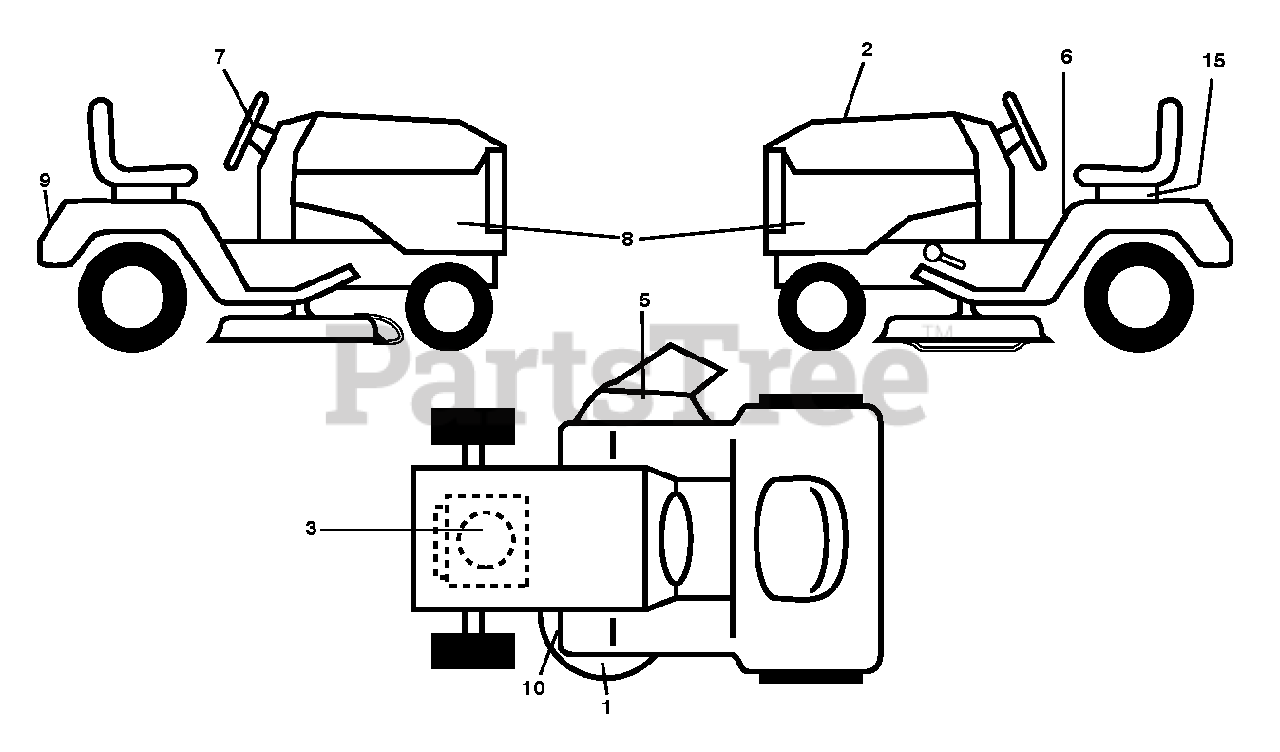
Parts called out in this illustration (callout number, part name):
1	DECAL.PPRO.10YRDECKWAR.POP
2	DECAL.RPL.BSM31.PB.TLW.46C.K46
3	Decal, Engine BS 17_5PB DOM 381669
5	DECAL, DECK DEFLECTOR, WARNING
6	DECAL.FENDER.WARNING.ENGLISH
7	DECAL.STRWHL.STDSQ.PPRO.YEL.17
8	DECAL.SDPNL.PP175H46.BLK.PPRO
9	Decal, REARFNDR Logo BLK 2017
10	DECAL.V-BELT.SCH.42/46"MEC/ELE
15	DECAL BTRY SYMBOLS
